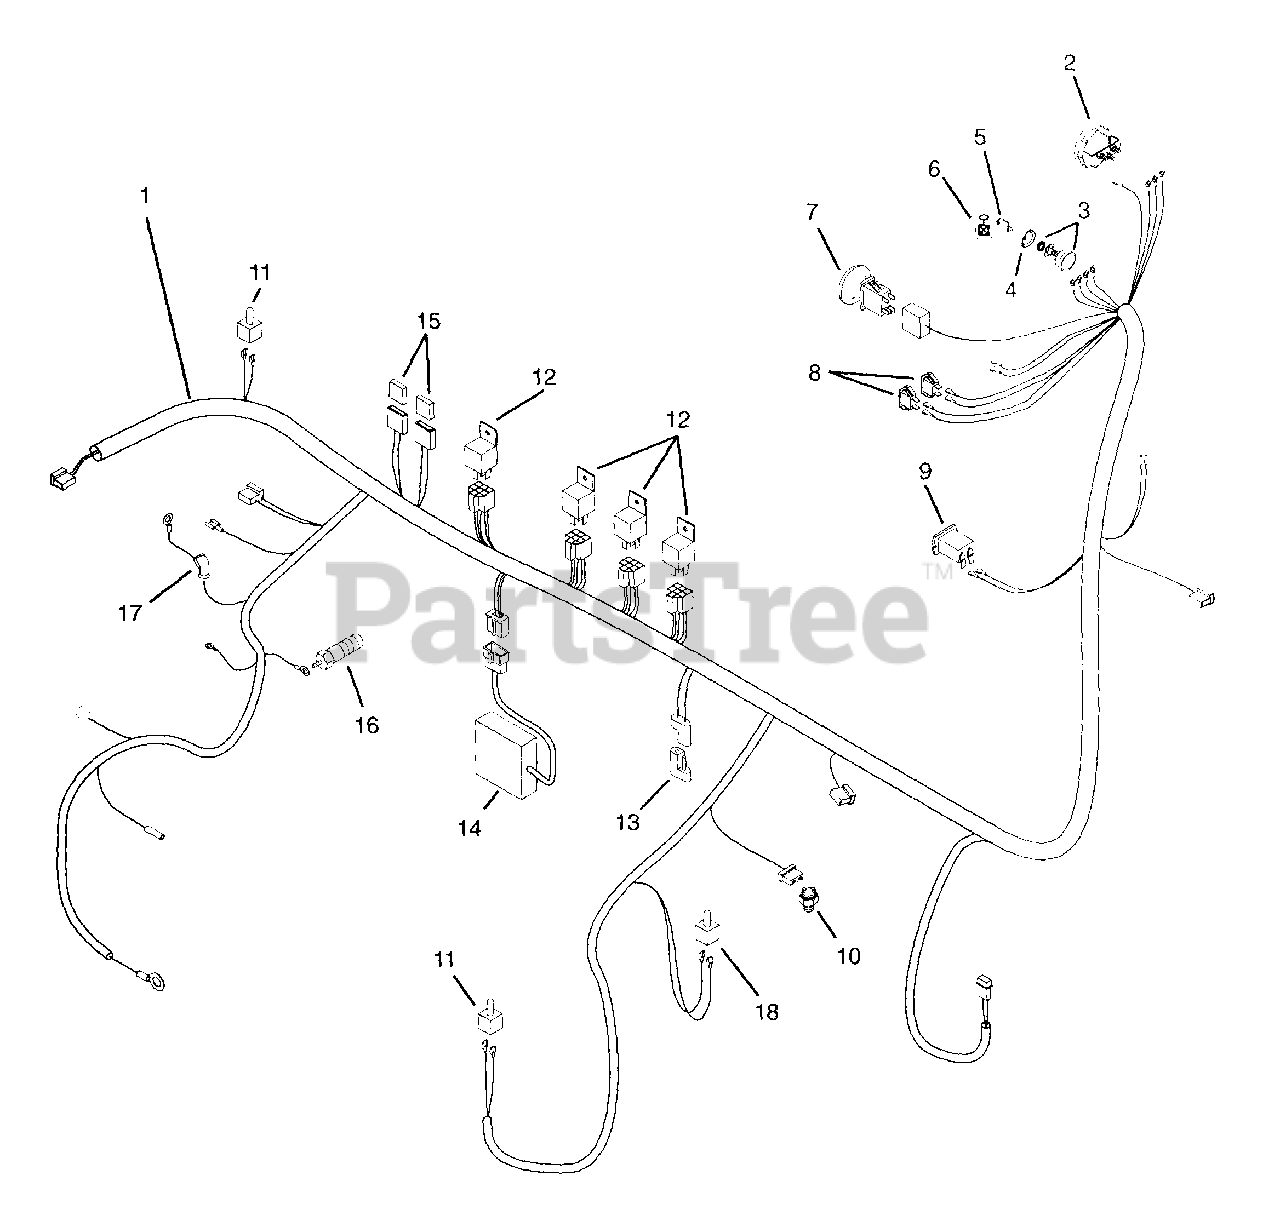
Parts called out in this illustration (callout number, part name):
1	Harness, Wiring
2	Gauge, Temperature
3	Switch, Ignition
4	Cap, Ignition Switch
5	Ignition Key Set
6	Key Chain
7	Switch, Clutch with Retaining Ring
8	Light, Indicator
9	Hour Meter
10	Switch, Neutral N.O.
11	Switch, Interlock
12	Relay
15	Fuse 30 Amp
16	Temperature Sender
18	Switch, Interlock N.C. (Parking Brake)
